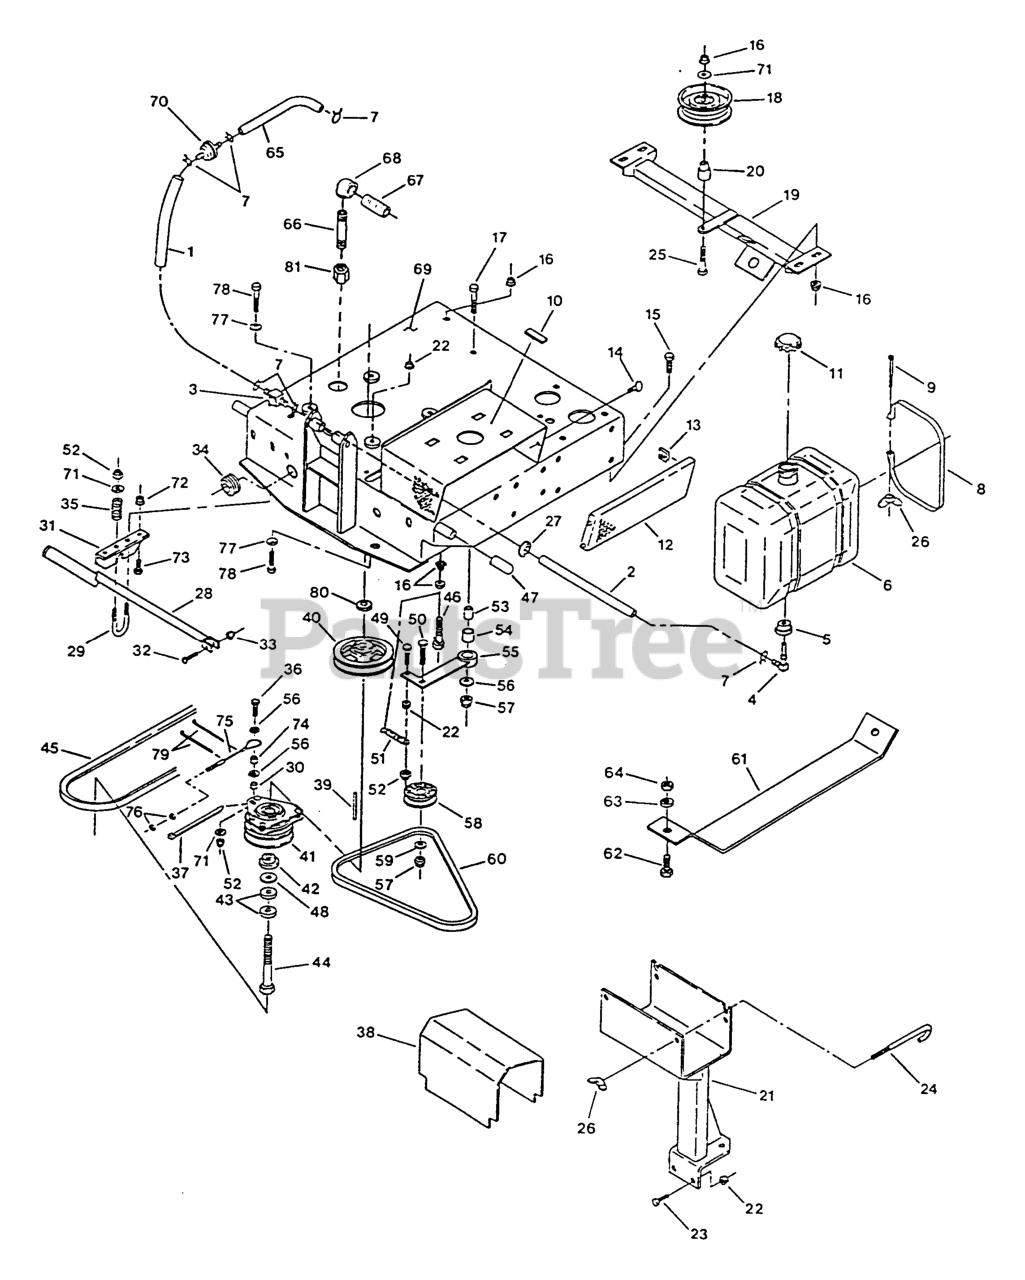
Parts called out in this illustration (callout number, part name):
1	FUEL LINE
3	VALVE-FUEL
4	ELBOW-TANK, FUEL
7	CLAMP
9	SCRW,MACH CRPH
10	PAD,PLASTIC TANK
11	CAP-FUEL
13	NUT,RETNR UTYP 1/4-20
14	SCREW,REGTHMB,
19	WLD,CROSSMEMBER
20	BUSHING,IDLER
21	WLD,BATTERY MOUNT
24	BOLT - HOLD DOWN
26	WINGNUT
27	GROMMET
30	SPACER,CLUTCH ANCHOR
34	GROMMET
35	SPRING-COMPRESSION
37	TIE-PLASTIC
40	SHEAVE,4.25 OD A
42	BUSHING,CLUTCH KEEPER
43	WASHER-SPRING
45	BELT,DECK DRIVE
47	GRIP-LEVER, DRIVE
51	SPRING,EXTENSION
53	BUSHING,STEEL
54	BUSHING,IDLER ARM
55	WLD,IDLER ARM HYDRO
58	IDLER,PULLEY
60	BELT,A TRANS DRIVE
61	PLATE-SKID
67	NIPPLE,PIPE
68	ELBOW-90 DEG
77	WASHER-SPRING
79	TIE-CABLE
81	CAP-HEX
